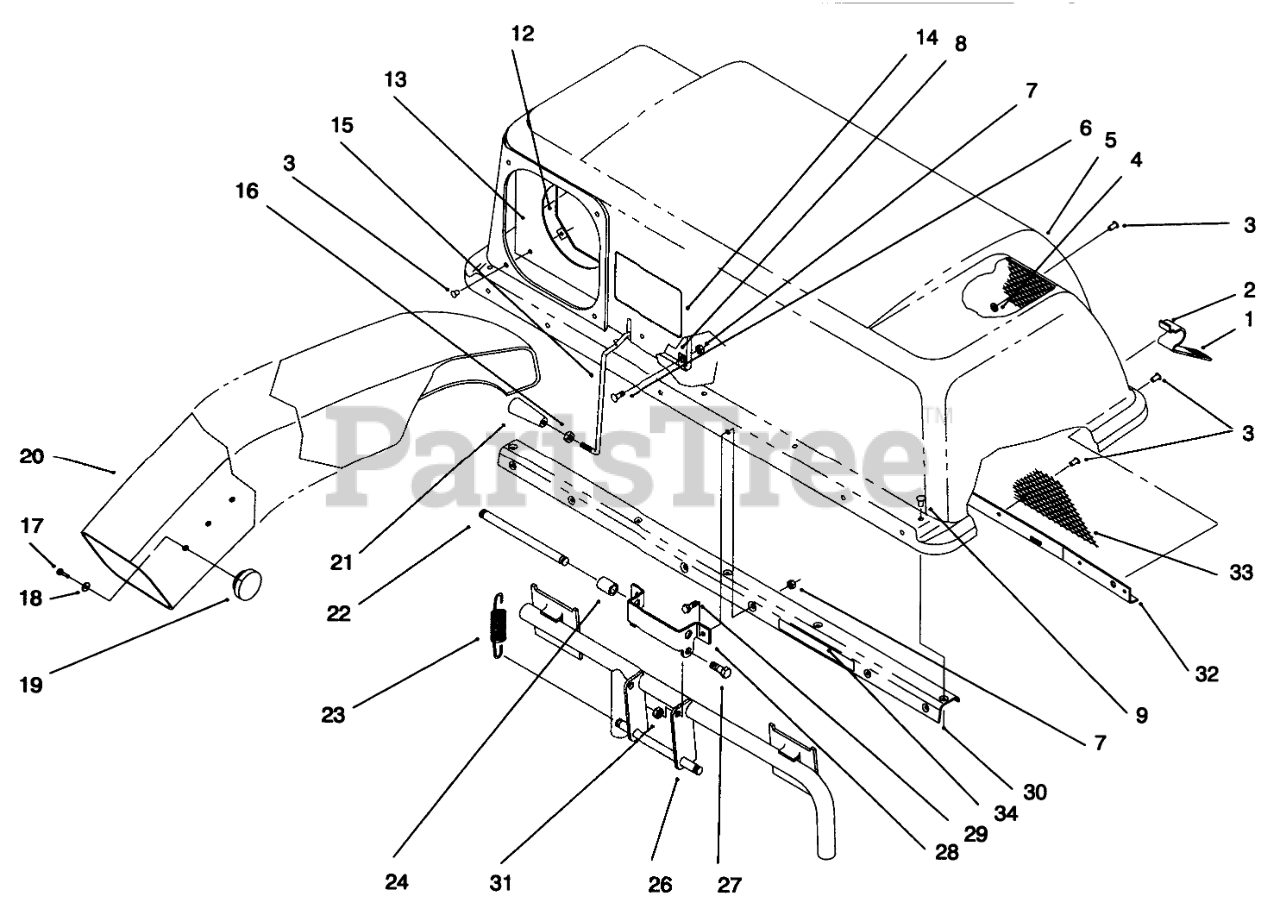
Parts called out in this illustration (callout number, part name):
2	Latch-Bag
3	RIVET-BLIND
4	WASHER-FLAT
5	TOP-BAGGER
6	SCREW-PPH
7	NUT-LOCK, NI
8	CLAMP
12	CLAMP-SEAL
13	SEAL-CHUTE
14	DECAL
15	FEELER-FILL, BAG
16	NUT-JAM
17	SCREW-PPHTF
18	WASHER-PLAIN
20	CHUTE-DISCHARGE
21	HANDLE-TAPERED
22	PIN-SPRING
23	SPRING-EXTENSION
24	Spacer
26	FRAME ASM
27	SCREW-HH
28	HINGE-BAG TOPB
29	SCREW-HH
30	Stiffener Assembly (Incl. Ref. #34)
31	NUT-LOCK, NI
32	Screen Support
33	SCREEN-BAGGER
34	DECAL-CAUTION
